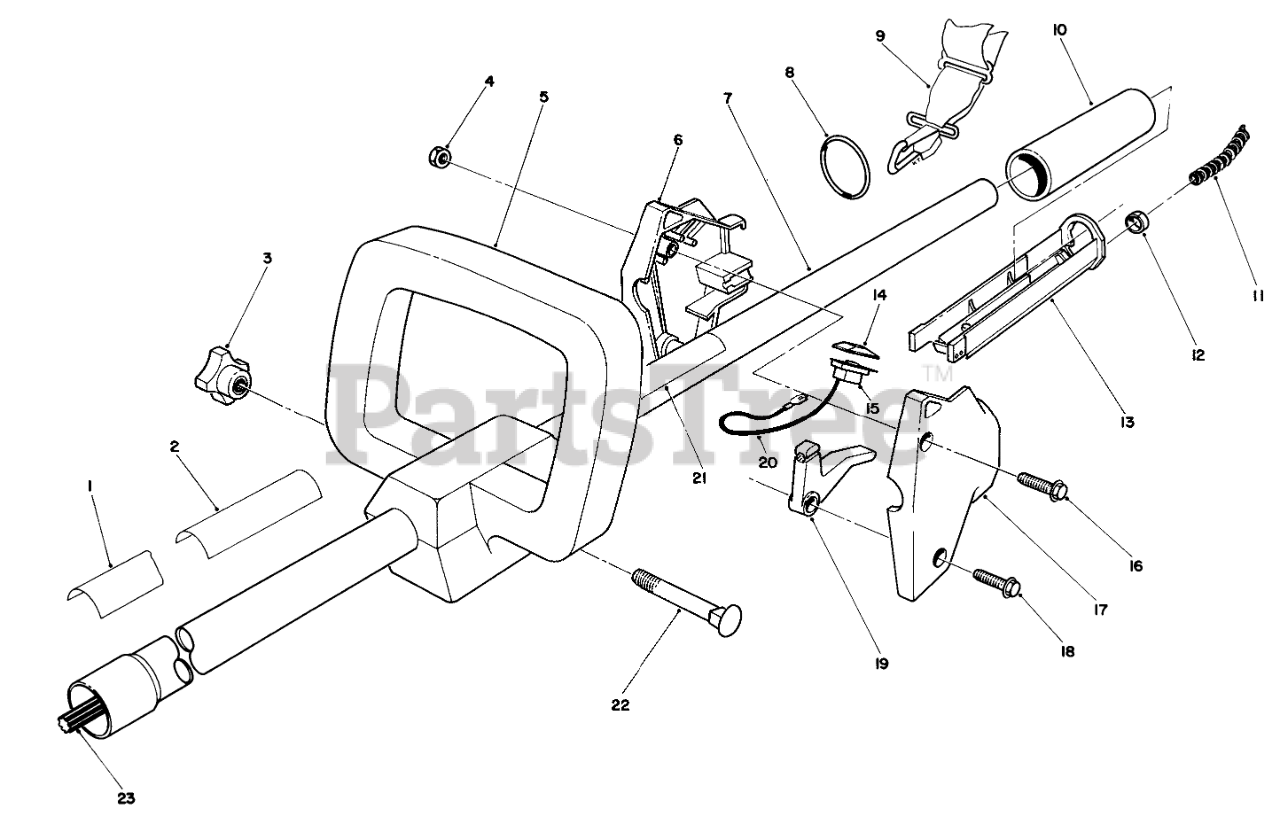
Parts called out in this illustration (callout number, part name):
1	DECAL - TC3100
2	DECAL-INSTRUCTION
3	Knob
4	NUT-LOCK, NI
5	HANDLE SECONDARY
6	THROTTLE HSG.R H
7	TUBE ASSEMBLY
8	RING-HARNESS
9	Harness-Shoulder
10	GRIP - RUBBER
11	CABLE COVER
12	RING FITTING
13	TROUGH 1"
14	SWITCH COVER-BLACK
15	SWITCH
17	THROTTLE HSG. L H
18	SCREW-HWH
19	THROTTLE LEVER
20	WIRE ASM
21	Decal Danger
22	BOLT-CARRIAGE
23	SPLINE SHAFT
